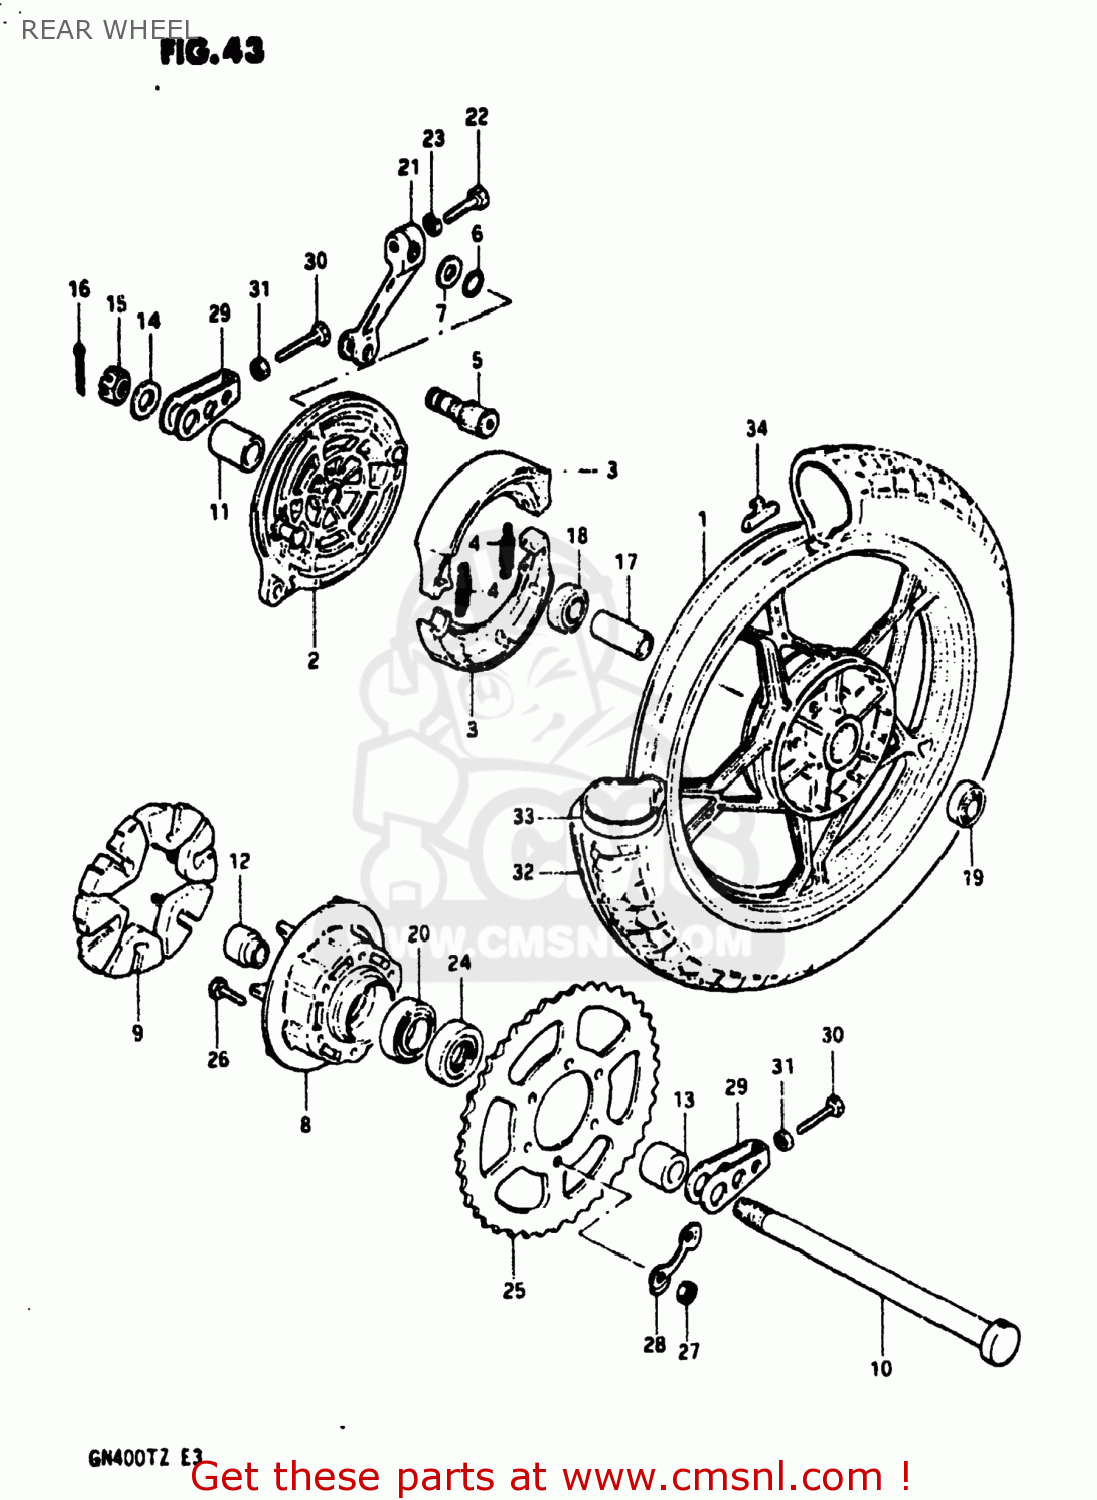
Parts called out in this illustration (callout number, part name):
1	WHEEL,REAR
2	PANEL,REAR HUB
3	SHOE,BRAKE
4	SPRING
5	CAM,FRONT BRAKE
6	O-RING,BOSS
7	WASHER (15X24X1.6)
8	DRUM,REAR SPROCKET MOUNT
9	ABSORBER,RR HUB SHOCK
10	AXLE,REAR
11	SPACER (17.5X28X49.8)
12	SPACER,REAR HUB BEARING
13	SPACER(17X30.5X22.3)
14	WASHER (17X30X3.2)
15	NUT
16	PIN,COTTER
17	SPACER (17.6X24X57)
18	BEARING
19	BEARING
20	BEARING
21	LEVER,RR BRAKE CAM
22	BOLT
23	LOCK WASHER
24	SEAL,OIL(30.5X52X8)
25	SPROCKET,REAR (NT:37)
26	BOLT
27	NUT
28	WASHER
29	ADJUSTER,CHAIN
30	BOLT 8X50
31	NUT
32	TIRE
33	TUBE ASSY,WHEEL,INNER 4.60-16
34	BALANCER,WHEEL
